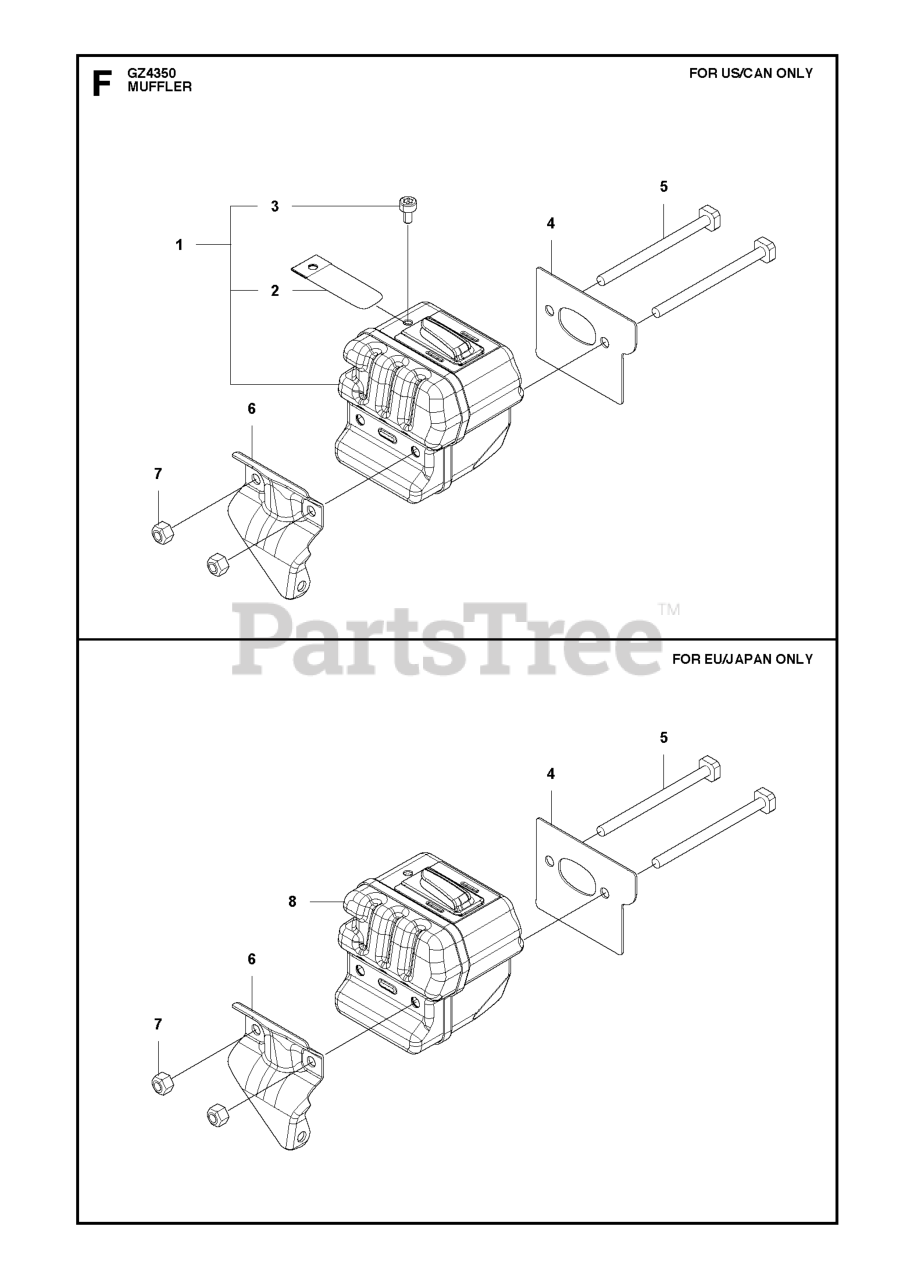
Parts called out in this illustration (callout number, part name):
1	MUFFLER ASSY
2	SPARK AARRESTOR SCREEN
3	BOLT
5	BOLT
6	BRACKET MUFFLER
8	MUFFLER
